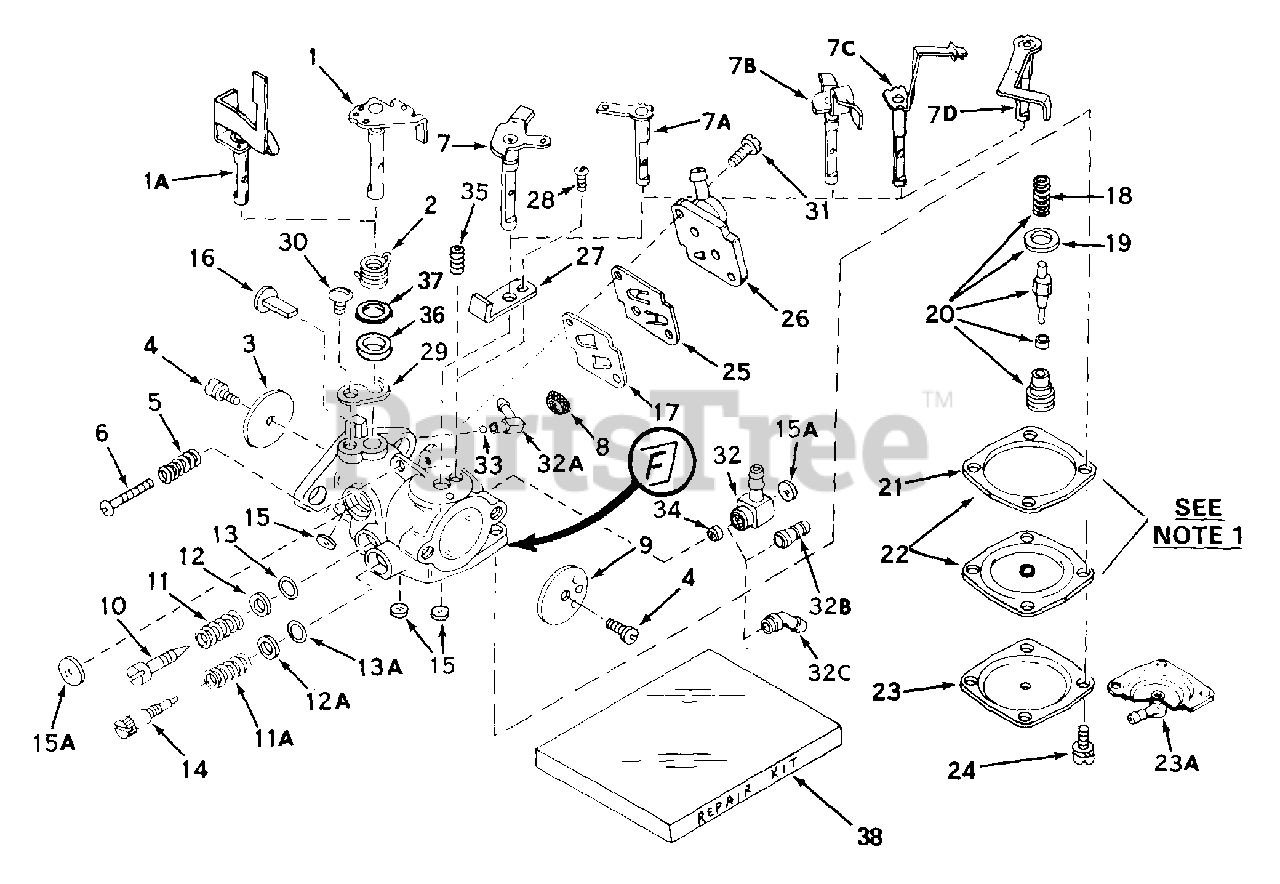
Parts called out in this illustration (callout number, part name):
1	"Shaft & Lever Assy., Throttle
2	Spring, Throttle return
3	Shutter, Throttle
4	Screw, Throttle & choke shutter
5	Spring, Idle speed
6	Screw, Idle regulating
7A	Shaft & Lever Assy., Choke
8	Screen, Filter
9	Shutter, Choke
10	Screw, Idle adj.
11	Spring, Adj. screw
11A	Spring, Adj. screw
12	Washer, Adj. screw
12A	Washer, Adj. screw
13	"O" Ring, Adj. screw
13A	"O" Ring, Adj. screw
14	Screw, Main adj.
15	Plug, Welch
16	Element, Pump
17	Gasket
18	Spring, Valve
19	Gasket, Valve seat
20	Inlet Needle, Seat, Spring & Gasket A ssy.
21	Gasket, Diaphragm
22	Diaphragm Assy.
23	Cover, Diaphragm
24	Screw, Diaphragm cover
25	Valve, Flap
26	Cover Assy., Valve
27	Spring, Detent
28	Screw, Detent spring
29	Retainer, Throttle shaft
30	Screw, Retainer
31	Screw, Cover
38	Repair Kit
